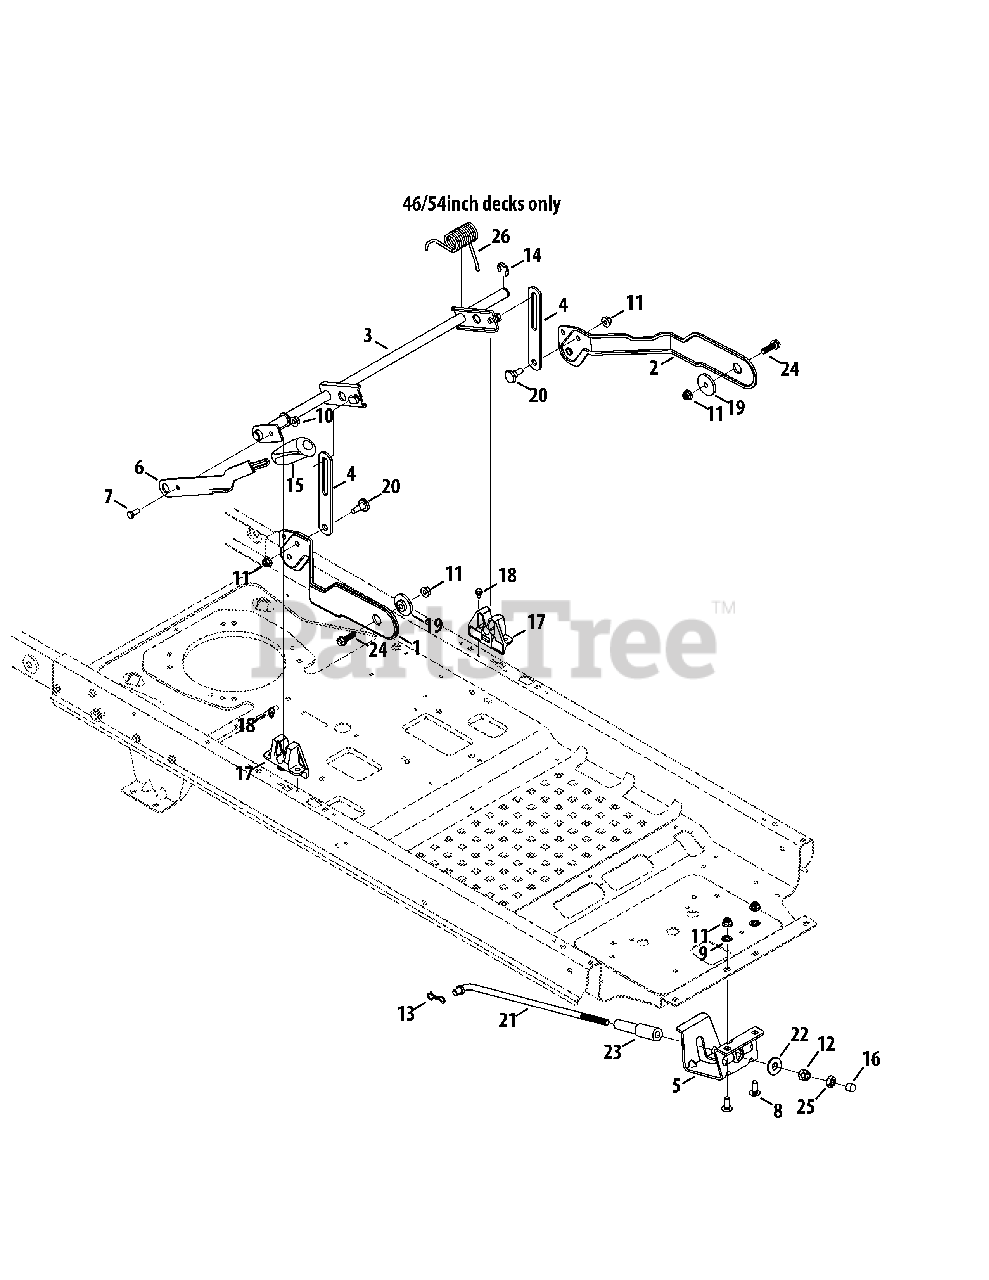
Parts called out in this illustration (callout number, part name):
1	Deck Lift Plate, RH
2	Deck Lift Plate, LH
3	Deck Lift Shift Assembly
4	Lift Link Plate
5	Rod Support Mounting Bracket
6	Deck Lift Handle
7	Hex Cap Screw, 5/16-18 x .75
8	Carriage Bolt, 3/8-16 x 1.00
9	Push Nut, 3/8
10	Flange Lock Nut, 5/16-18
11	Flange Lock Nut, 3/8-16
12	Hex Nut, 1/2-13
13	Bow-Tie Cotter Pin
14	E-Type Ring, .750
15	Grip, .50 ID
16	End Cap
17	Deck Lift Bracket
18	Shoulder Screw, .500 x 1/4-20
19	Shoulder Spacer, .854 x .232
20	Shoulder Screw, .500 Dia. x .434
21	Deck Lift Rod
22	Deck Lift pivot Cup
23	Nylon Sleeve, .55 ID x 4.50 LG
24	Screw, 3/8-16 x 1.00
25	Jam Nut, 1/2-13
26	Torsion Spring, 1.323 ID x 2.83 LG
